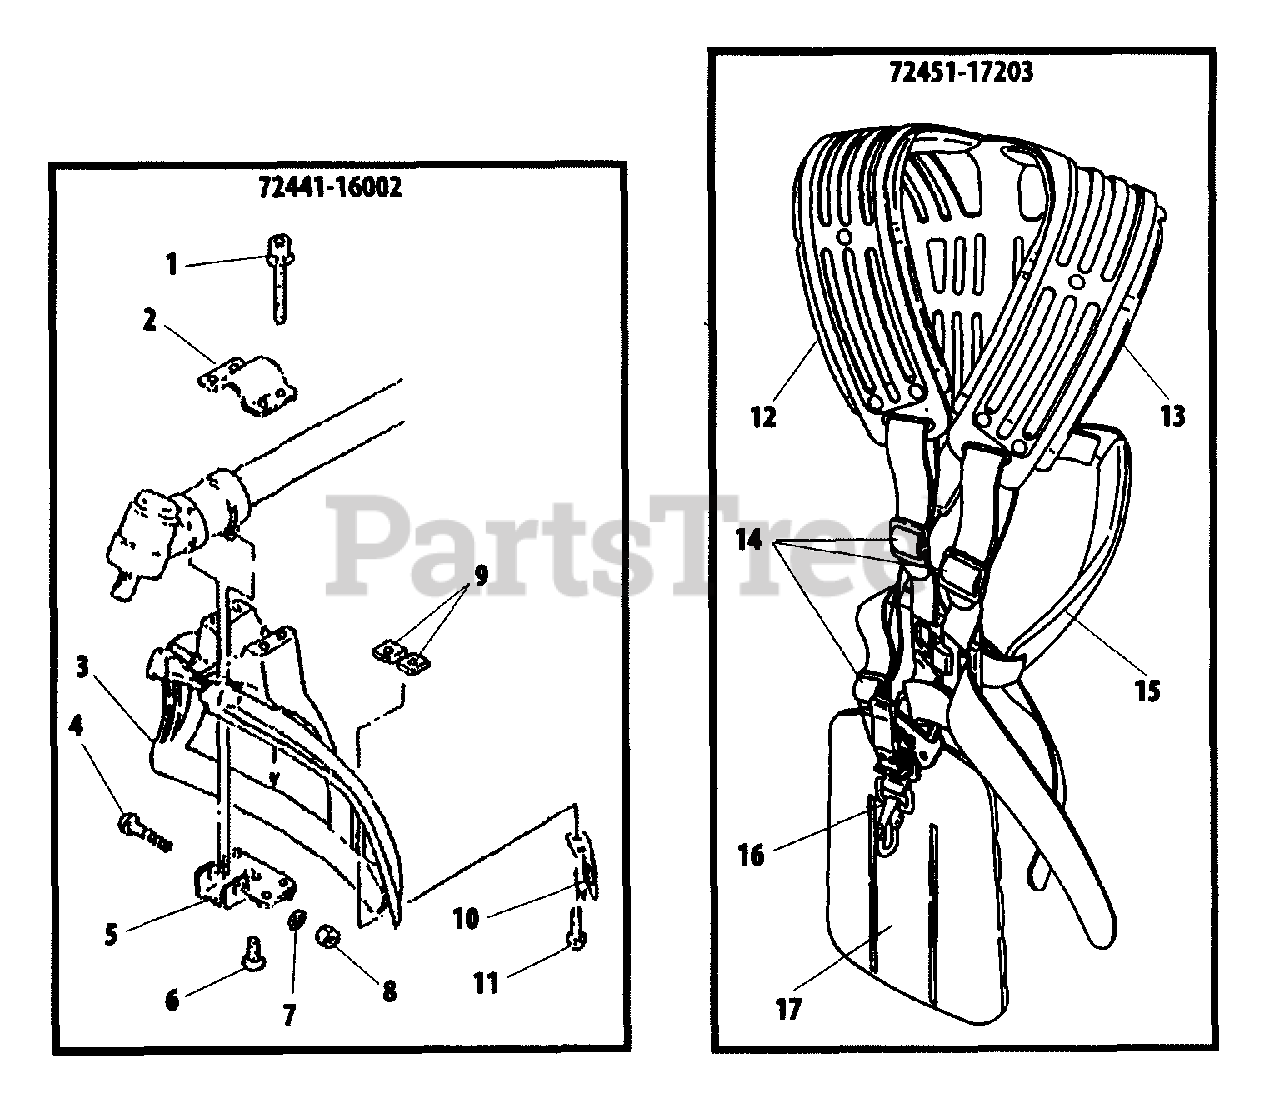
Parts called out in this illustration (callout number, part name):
1	BOLT M5×45
2	CLAMP, UPPER
3	SHIELD, DEBRIS
4	BOLT M6×40
5	CLAMP, LOWER
6	SCREW HILO 4×10
7	WASHER 6.5×13×1
8	NUT, HEX M6
9	NUT M5
10	CUTTER
11	BOLT M5×16
12	PAD, SHOULDER - RIGHT
13	PAD, SHOULDER - LEFT
14	BUCKLE
15	PAD, SHOULDER
16	HOOK
17	PAD
72441-16002	DEBRIS SHIELD KIT
72451-17203	HARNESS ASSY
